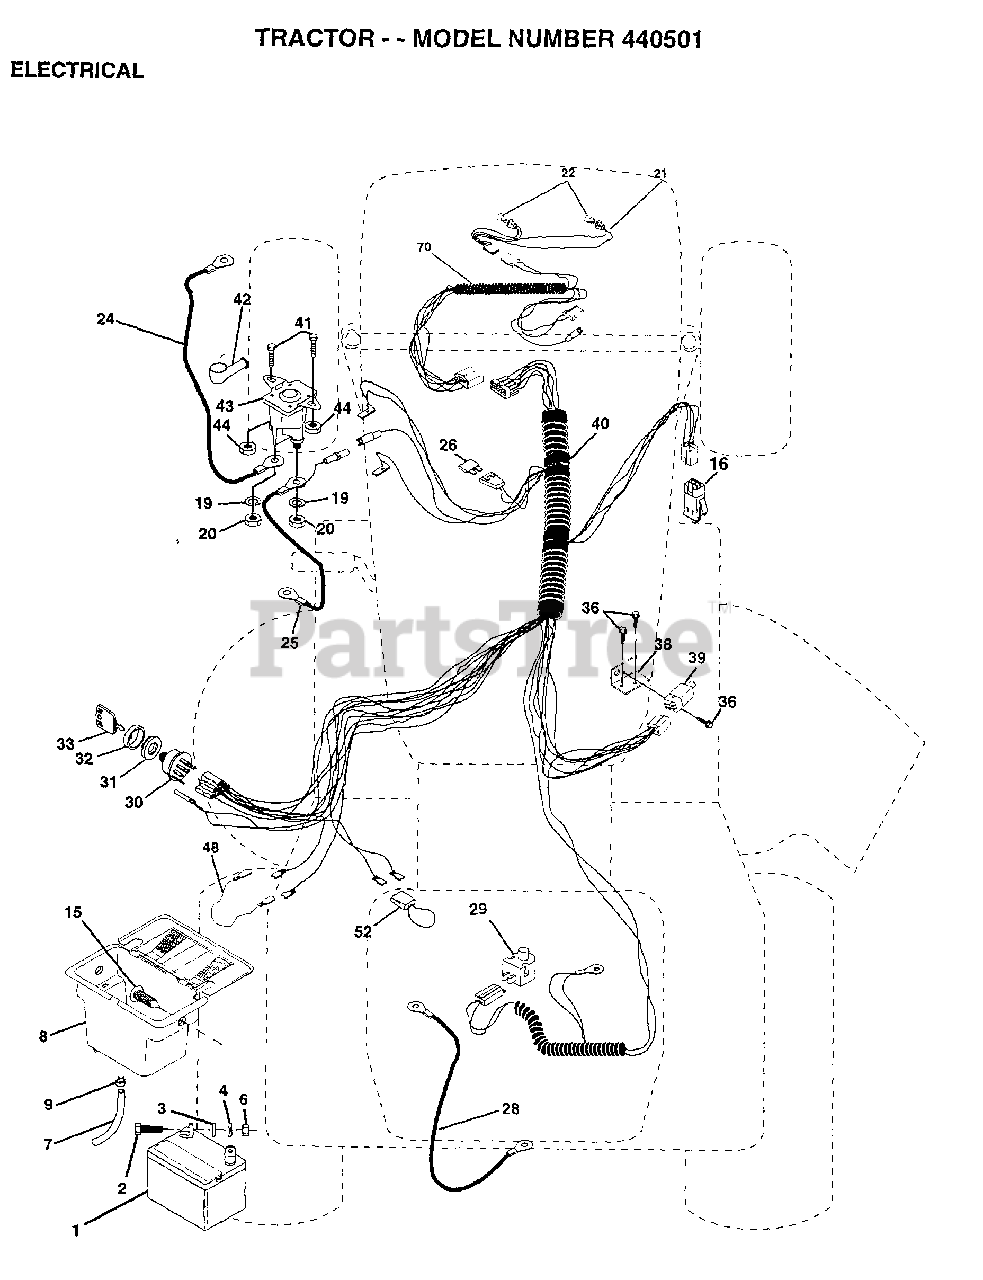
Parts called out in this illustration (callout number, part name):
2	BOLT LT
3	WASHER
4	LOCKWASHER
7	TUBE T
9	HOSE CLAMP T
15	FASTNER.SNAP-IN
16	SWITCH INTERLOCK
20	NUT
21	"HARNESS,LIGHT SOC"
22	HEADLAMP BULB
24	CABLE-BATTERY T
25	CABLE.BTRY.6GA.RD
26	FUSE HYT
28	CABLE T
29	SWITCH SEAT
30	SWITCH IGN 4POS
31	NUT IGNITION
32	COVER KEY SWITCH
33	KEY
36	SCREW
38	BRACKET SWITCH IN
39	SWITCH INTERLOCKT
40	HARNESS.IGNITION
41	BOLT HXHD FIN
44	NUT HXKEP 1/4X20
48	ADAPTER AMMETER
52	PROTECTION LOOP
70	HARNESS.ENG.LT.
